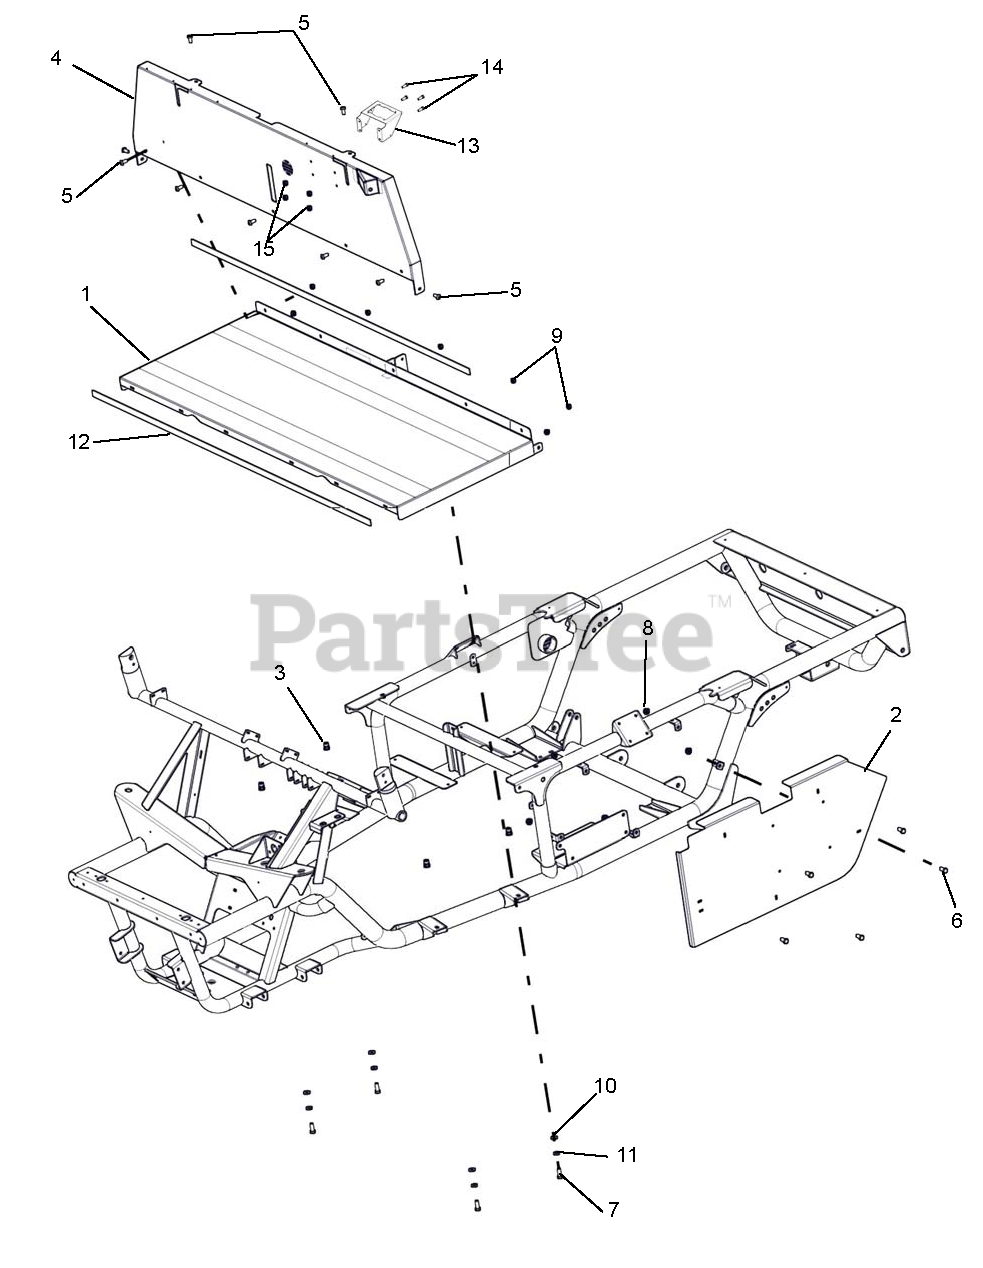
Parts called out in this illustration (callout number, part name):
1	WLDT-FLOOR
2	SIDE PANEL, WIDE
3	NUTZERT, 5/16-18 X .667 HEX Y
4	WLDT, KICK PANEL
5	SCR-MCH .25-20X.75 TXTR YWZC
6	@BLT-HEX .31-18X.75 GR5 YWZC
7	@BLT-HEX .31-18X1.00 GR5 YWZC
8	@NUT-LK-TOP-FLG .31-18 YWZC
9	@NUT-LK-TOP-FLG .25-20 YWZC
10	WASHER FLAT 5/16 HARD ASTMF436
11	@WSHR-LK .31X.078 REG YWZC
12	FOAM RUBBER 3/16X3/4 THK W/PSA
13	BRKT, MODULE EPA FUSE/RELAY
14	TTHMS 1/4-20X3/4 ZNYCR
15	NUT HEX FLG TL 1/4-20 ZNYCR
